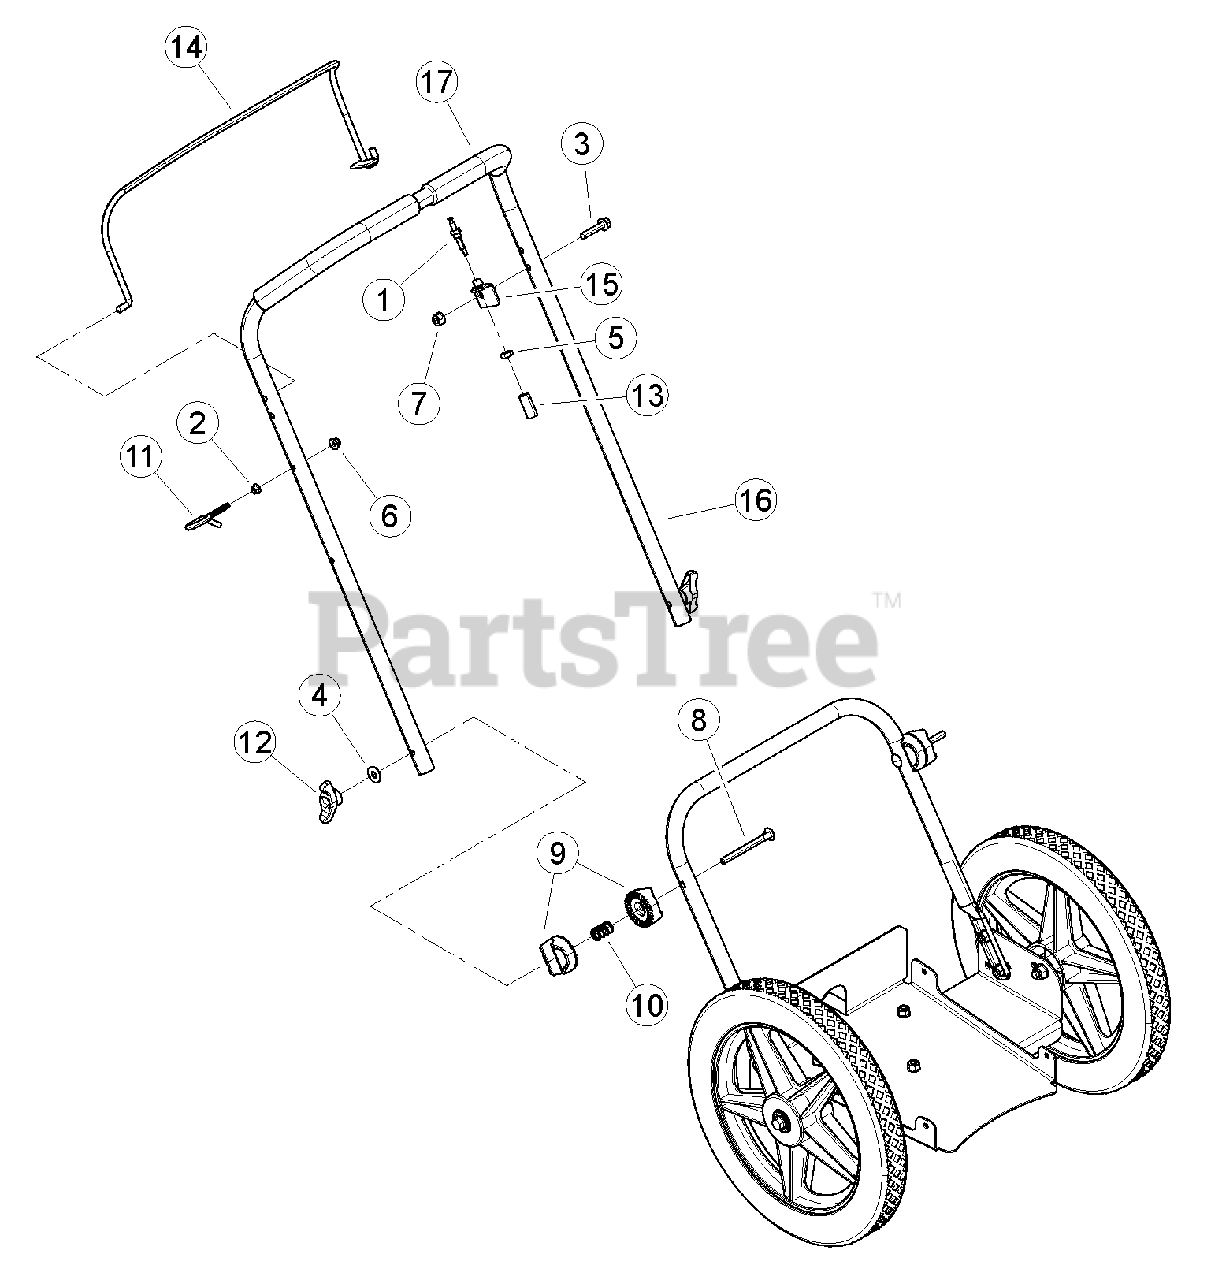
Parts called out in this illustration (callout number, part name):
1	SWITCH, ENGINE KILL
2	NUT, 1/4"-20 SERRATED FLANGE NC ZP
3	BOLT, 5/16 X 1-1/2 FLANGE NC
4	WASHER, 5/16 FLAT
5	NUT, 3/8-24 JAM
6	NUT, 1/4-20 NYLOCK FLANGE
7	NUT, 5/16-18 NYLOCK FLANGE
8	BOLT, 5/16-18 X 3-1/2 LONG NECK GR5 CRG ZP
9	RETAINER, HANDLEBAR ADJUSTMENT
10	SPRING, RETAINER COMPRESSION
11	GUIDE, RECOIL ROPE
12	KNOB, 5/16-18 FEEM TEE
13	TUBING, HEAT SHRINK 1/2" X 1-1/4" 2:1 RATIO
14	ASSEMBLY, BAIL HW TRIMMERS
15	BRACKET, TRIMMER KILL SWITCH
16	ASSEMBLY, UPPER HANDLE BAR WITH GRIPS
17	PAD, FOAM HANDLE BAR
